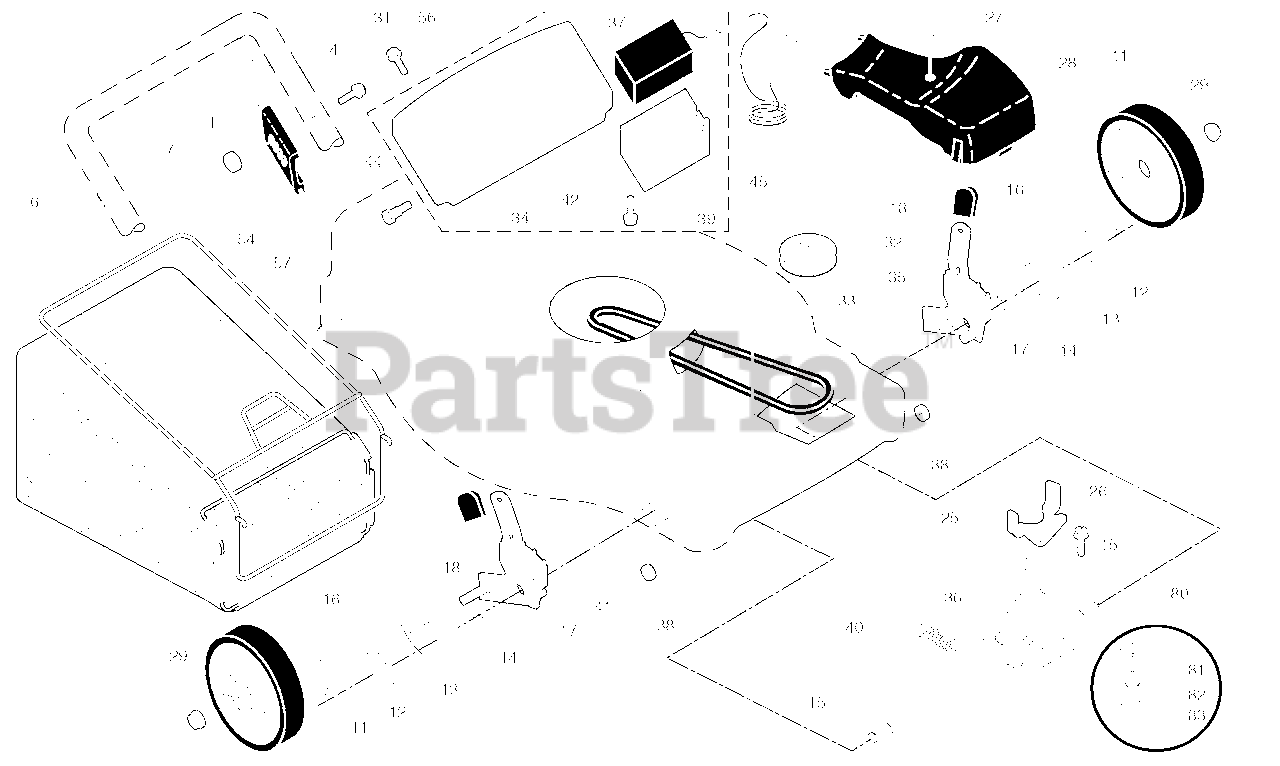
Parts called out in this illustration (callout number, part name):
1	Drive Control Assembly
4	Screw, Hex Head
6	Bar, Drive Control
7	Nut, Hex
11	Wheel & Tire Assembly, Front
12	E-Ring
13	Pinion
14	Dust Cover
15	Pawl, Drive
16	Washer, Flat 3/8
17	Bearing, Wheel Adjuster
18	Selector Knob
25	Belt Keeper
26	Screw, Hi-Lo Thread
27	Screw, Pan Head, Self-Tapping #10-24 x 2-3/4
28	Drive Cover
29	Locknut, Hex
31	Screw, Trimplate
32	Pulley, Drive
33	V-Belt
34	Trimplate
35	Kit, Wheel Adjuster, LH
36	Gear Case Assembly, Complete
37	Battery
38	Locknut 1/4-20
39	Battery Box
40	Spring
41	Kit, Wheel Adjuster, RH
42	Screw, Battery Box
44	Screw, Trimplate
45	Charger, Battery
54	Grassbag Assembly
56	Trimplate, Battery Box and Battery Assembly
57	Frame, Grassbag
80	Water Washout Assembly
81	Fitting, Hose, Water Washout
82	Washer, Lock, Internal Tooth
83	Locknut, Hex, with O-Ring
